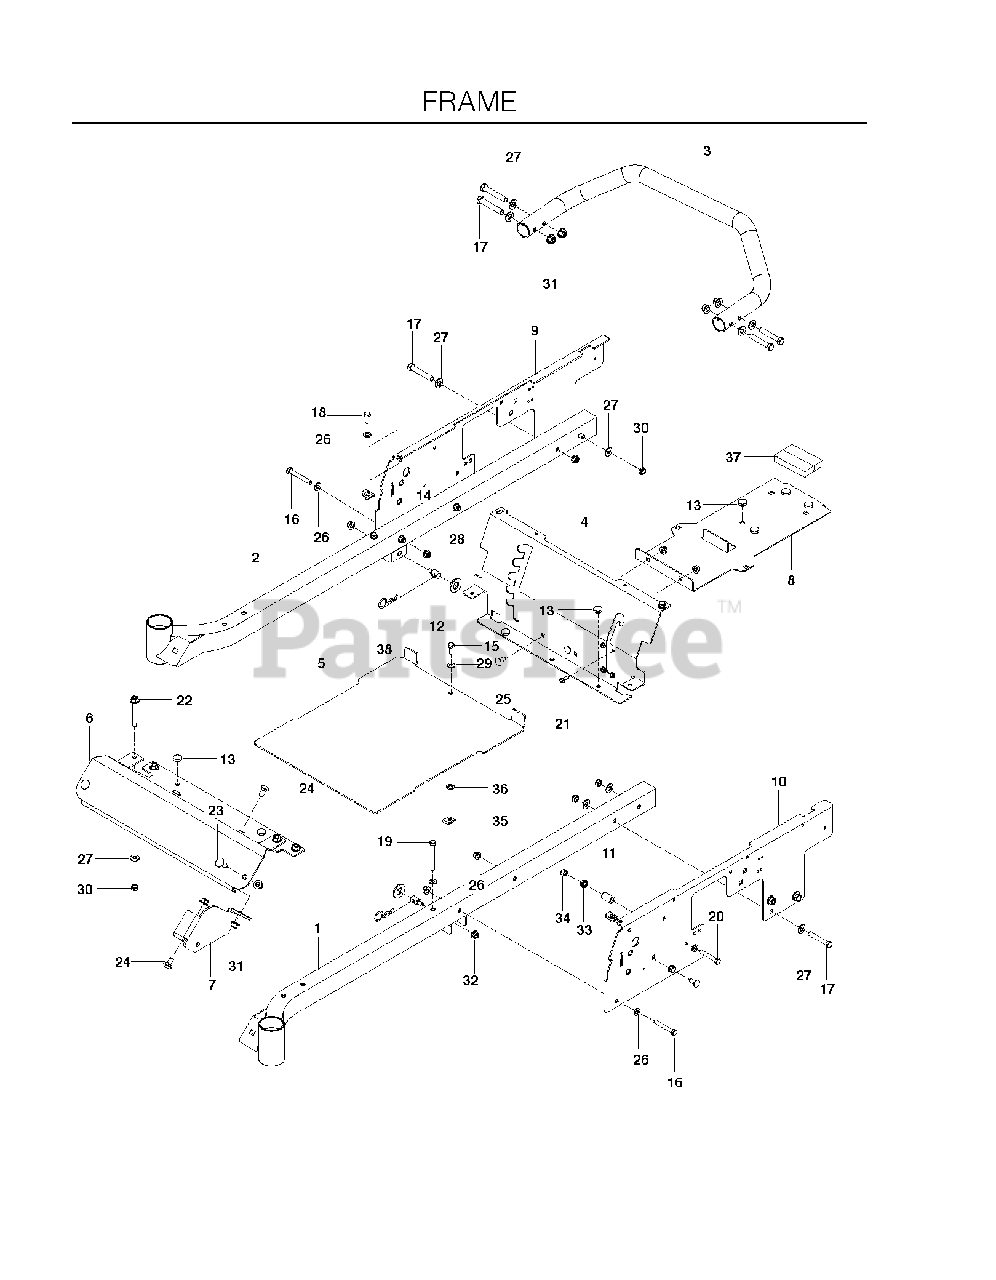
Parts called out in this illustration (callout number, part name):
1	FRAME, TUBE, LH, BLUE
2	FRAME TUBE, RH, BLUE
3	IMPACT BAR, BLUE
4	PANEL, SEAT SUPPORT, BLUE
6	FOOT REST, BLUE
7	BRACKET, FRONT DECK, BLK
8	SUPPORT, TANK/BATT, BLK
9	PLATE, RH SIDE, BLUE
10	PLATE, LH SIDE, BLUE
11	BUSHING
12	STUD.FASTNER.W/D.ANTI-
13	GROMMET, BUMPER
14	U-CLIP 5/16-18 NUT RETAINER
15	HCS 1/4C X 3/4 HCS
16	CAPSCREW
17	HCS 3/8C X 2 1/4
18	HCS 5/16C X 3/4
19	HCS 5/16C X 2-3/4
20	HCS 5/16-18X2
21	SCREW 1/4 X 5/8
22	ENGINE BOLT, SPECIAL
23	RHSNB 3/8C X 1
24	RHSNB 3/8-16 X 3/4 GR5 ZD
25	BOLT 5/16C X 3/4" CARRIAGE
26	FLAT WASHER 5/16 SAE
27	WASHER 3/8 SAE FLAT
28	WASHER 5/8 FLAT
29	WASHER 1/4 SAE
30	NUT HEX 3/8-16 NYLON, THIN
31	NUT 3/8-16 HEX FLG NYLOC ZD
32	5/16-18 NYLOC FLANGE NUT
33	NUT 5/16C WHIZ
34	NUT 5/16 NYLOC
36	PALNUT 1/4
37	FOAM STRIP, FUEL TANK
38	HAIRPIN #4
